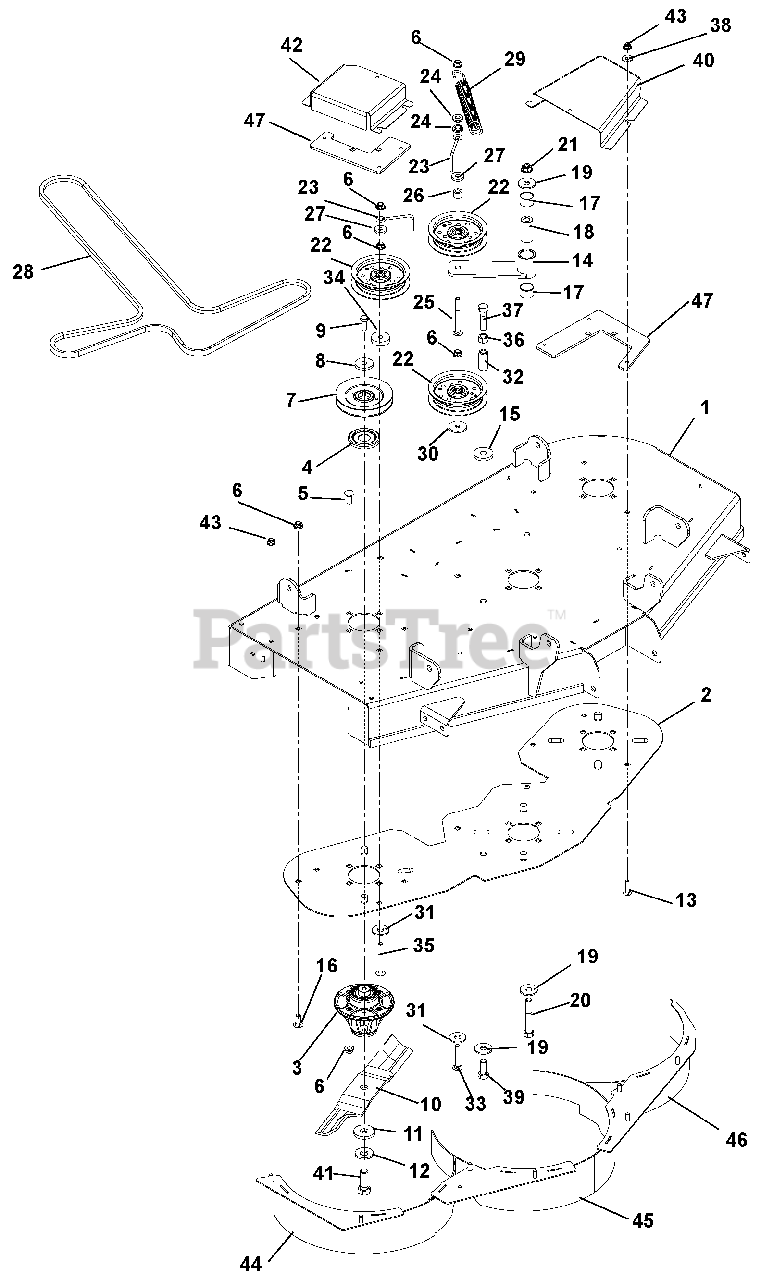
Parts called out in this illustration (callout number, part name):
1	XL – Deck Kit CE
2	Doubler Plate, 42" Deck
3	Spindle Assembly
4	Dust Cap
5	Bolt, Round Head Square Neck .38-16 x 1.25 Grade 5
6	Nut, .38-16 Nyloc Flange
7	Pulley, Spindle
8	Washer, Flat Steel .406 x 1.50 x .245
9	Bolt, Hex .38-16 x 1.00 EP30
10	Blade, Mulch 14.50"
11	Washer, Flat .640 x 1.75 x .250
12	Washer, Bellville .63 x 1.625 x .14
13	Bolt, Serrated Hex Flange Washer Head .312-18 x .50
14	Idler Arm
15	Washer, Flat Steel .515 x 1.625 x .250 YZ
16	Bolt, Round Head Square Neck .38-16 x 1.00 Grade 5
17	Bearing, 1.00 x 1.12 x .75
18	Bushing, Spacer .505/.500 x .999/.996 x 2.05/2.03 Promaster
19	Washer, Flat Steel .511 x 1.441 x .125
20	Bolt, Hex .50-13 x 3.50 Grade 5
21	Nut .50-13 Nyloc Flange
22	Assembly, Idler 4"
23	Belt Finger
24	Bushing, Flange .406 x .88 x .270 x .140
25	Bolt, Round Head Square Neck .38-16 x 3.50 Grade 5
26	Bushing, Sleeve .391 x .688 x .52
27	Washer, Flat Steel .406 x 1.00 x .188
28	Belt, HA 127.12 Wrapped
29	Extension Spring
30	Washer, Flat Steel .39 x 1.5 x .125
31	Plate, Idler Mount Reinforcement
32	Nut, Coupling .50-13 x 1.75
33	Bolt, Round Head Square Neck .38-16 x 2.25 Grade 5
34	Spacer, .39 x 1.50 x .380
35	Bolt, Round Head Square Neck .38-16 x 3.50 Grade 5
36	Nut, Hex .50-13
37	Bolt, Hex .50-13 x 2.00 Grade 5
38	Washer, Flat Steel .38 x .875 x .083
39	Bolt, Hex .50-13 x 1.25 Grade 5
40	Belt Cover, Left
41	Bolt, Hex .62-18 x 1.75 Grade 8
42	Belt Cover, Right
43	Nut, .31-18 Nyloc Flange
44	Weldment, 42 Baffle Right Hand
45	Weldment, 42 Mulch Baffle (CTR)
46	Weldment, 42 Mulch Baffle Left Hand
47	Bracket, Belt Cover Mount - LHS
